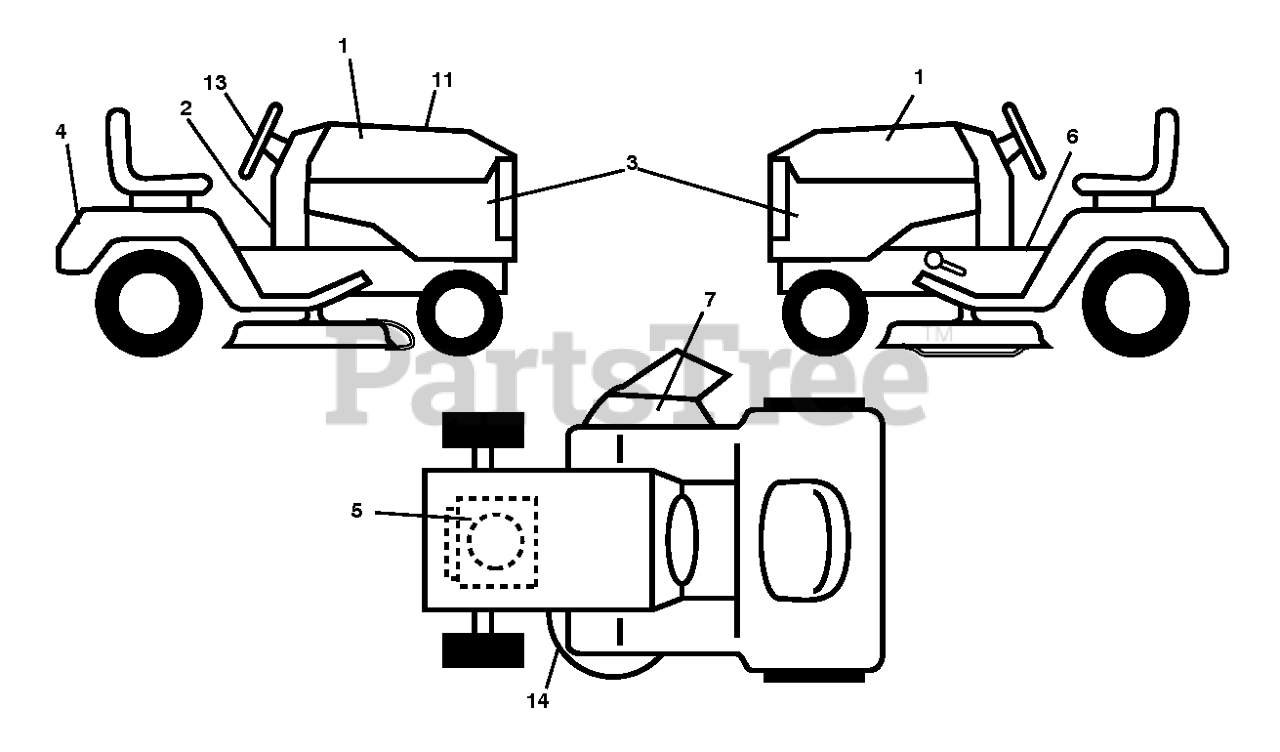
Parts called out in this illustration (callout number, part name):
1	DECAL.POULAN PRO.YEL/BLK.2017
2	DCL.WARNING.SPARK.IGNITION.CA
3	DECAL TRACTOR SIDE PANEL DECAL
4	DECAL.REARFNDR.LOGO.BLK.2017
5	DECAL.ENG.BS.20INTK.DOM.381707
6	DECAL.WARNING.2007.ENG/FR
7	DECAL, DECK DEFLECTOR, WARNING
11	DECAL DECAL.RPL.BSM40.INTK.TLW
13	DECAL.STRWHL.STDSQ.PPRO.BLK09
14	DECAL.V-BELT.SCH.42/46"MEC/ELE
